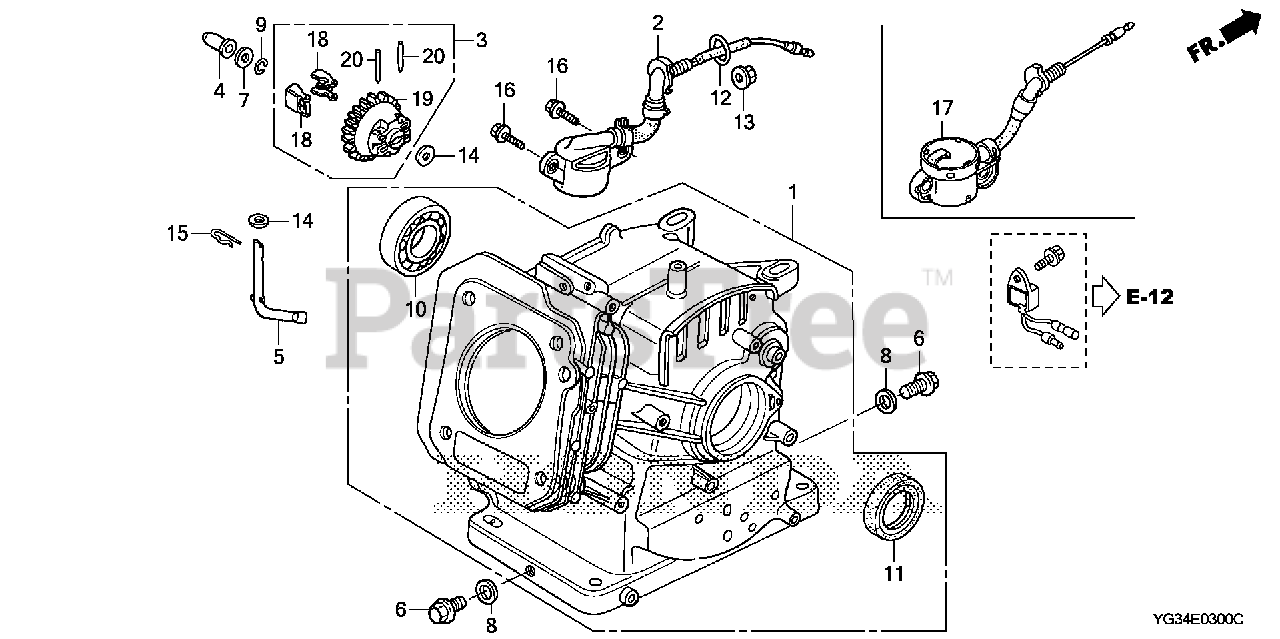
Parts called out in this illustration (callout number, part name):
1	CYLINDER ASSY. (OIL ALERT)
3	GOVERNOR ASSY.
4	SLIDER, GOVERNOR
5	SHAFT, GOVERNOR ARM
6	BOLT, DRAIN PLUG
7	WASHER, THRUST (6MM)
8	WASHER, DRAIN PLUG (10.2MM)
9	CLIP, GOVERNOR HOLDER
10	BEARING, RADIAL BALL
11	OIL SEAL (22X35X6)
12	O-RING (13.5X1.5) (ARAI)
12	O-RING (14MM) (NOK)
13	NUT, FLANGE (10MM)
14	WASHER, PLAIN (6MM)
15	PIN, LOCK (8MM)
16	BOLT, FLANGE (6X12)
17	SWITCH ASSY., OIL LEVEL
18	WEIGHT, GOVERNOR
19	HOLDER, GOVERNOR WEIGHT
20	PIN, GOVERNOR WEIGHT
